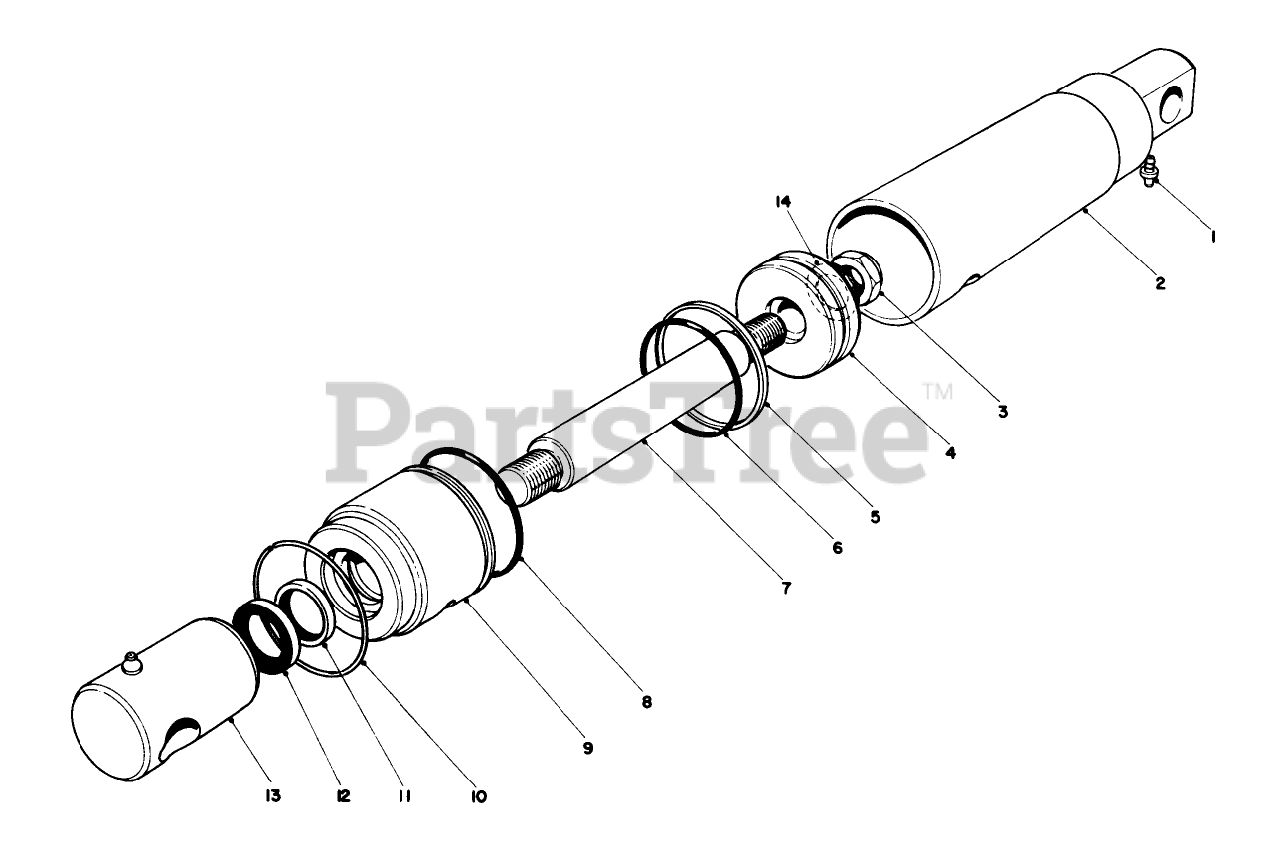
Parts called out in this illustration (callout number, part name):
1	FITTING-GREASE
2	Barrel Assembly
3	NUT-LOCK, NI
4	PISTON
5	Slipper Ring
7	Piston Rod
9	Bearing
10	Lock Ring
11	Seal ASM
12	Seal Wiper
13	Rod End
14	WASHER-THRUST
